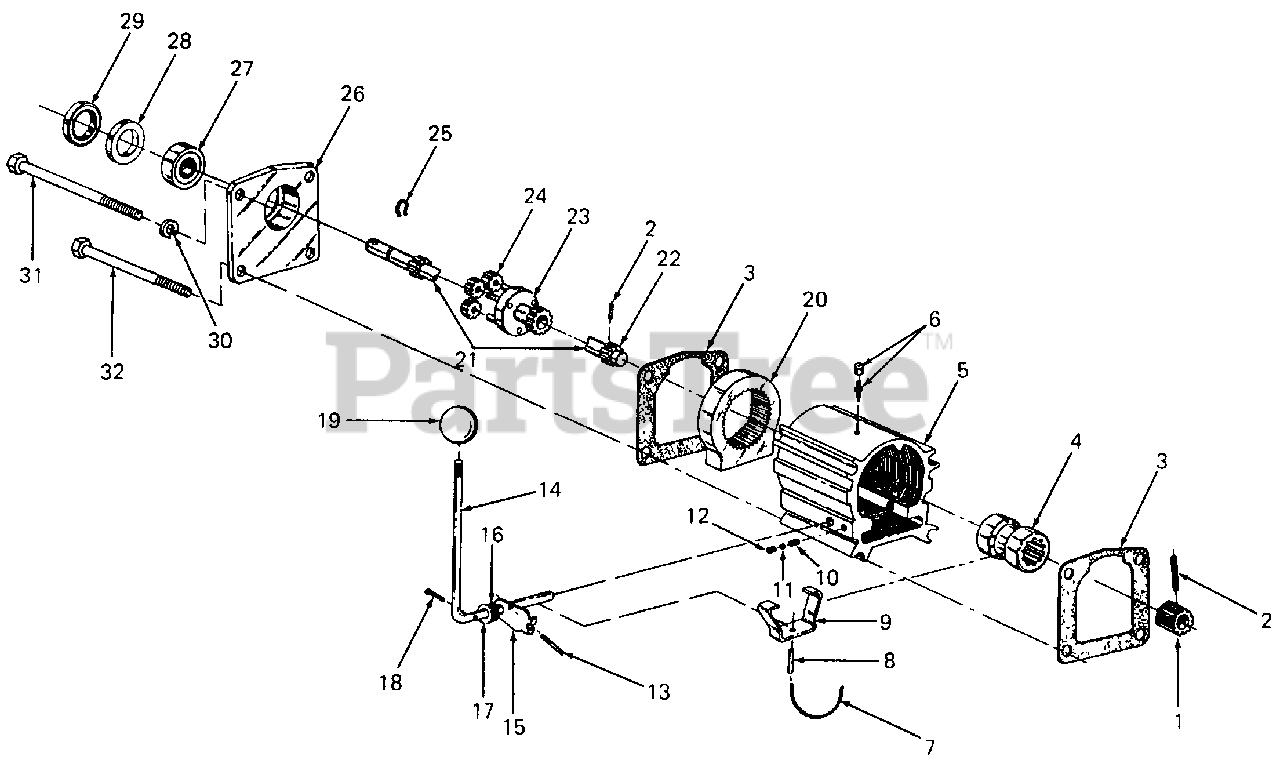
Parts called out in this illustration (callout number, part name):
1	Coupling, Driven
2	Pin, Spiral Spring, 1/4 Dia X 7/8Lg
3	Gasket
4	Collar, Shifter
5	Housing, Creeper
7	Wire, .062 Dia X 4.0 Lg
8	Pin, Roll, 3/16 Dia X 3/4 Lg
9	Yoke, Shift
10	Spring, Detent
11	Ball, Detent
12	Screw, Set, 5/16-18 X 1/4 Lg
13	Pin, Roll, 3/16 Dia X 1-5/8 Lg
14	Lever, Shift
15	Plate, Detent
16	O-Ring, 3/8 OD X .06 Thk
17	Washer, Flat, .385 X .62 X .03 Thk
18	Pin, Cotter, 3/32 Dia X 5/8 Lg
19	Knob
20	Race, Planetary
21	Shaft, Input
22	Coupling, Direct Drive
23	Carrier Assy, Planet
24	Gear, Planet - 12T
25	Ring, Snap, 5/8 Dia
26	Plate, Front
27	Bearing, Ball
28	Spacer, Shaft, 1.25 X 1.50 X .325 Thk
29	Seal, Oil
30	Washer, Lock, 3/8
31	Screw, Hex Cap, 3/8-16 X 5.0 Lg
32	Screw, Hex Cap, 3/8-16 X 4.5 Lg
